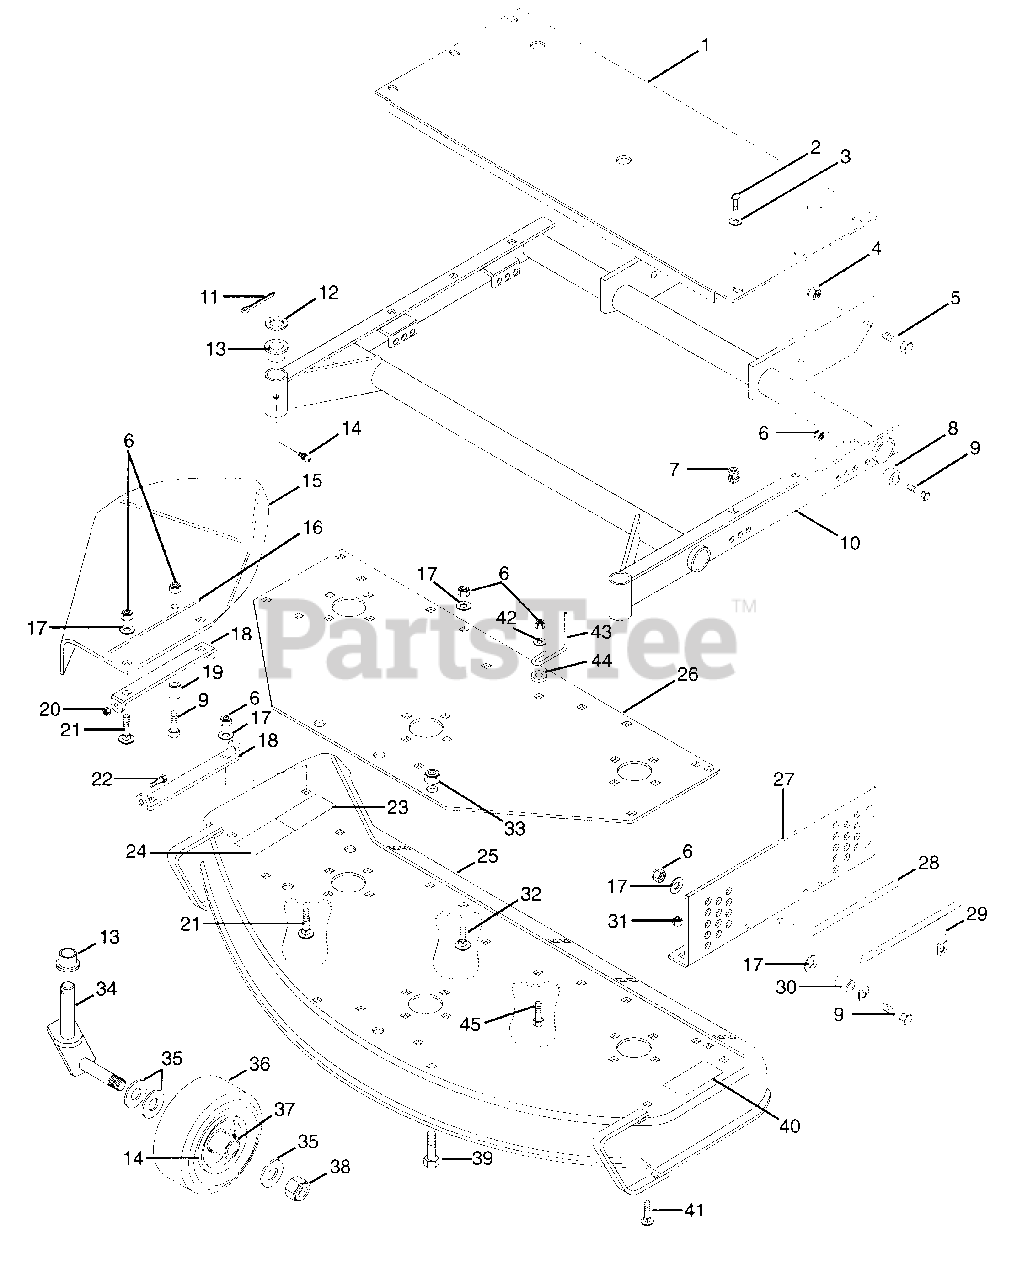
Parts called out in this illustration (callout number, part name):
1	Guard, 50" Mower Belt
2	Screw-Tapping .25-20 x .50
3	Washer-Flat-Steel .281 x .620 x .065
4	Nut-Locking-Nylon .625-11 Grade 2
5	Bolt-Hex .625-11 x 1.50
6	Nut-Locking-Nylon .375-16 Grade 2
7	Grommet, Plastic
8	Bushing .391 x .626 x .670
9	Bolt-Hex .38-16 x 1.50 Grade 5
10	Mower Frame, 50", Pro 150
11	Pin-Cotter .188 x 1.50
12	Washer-Hardened Trust 1.002 x 1.552 x .030
13	Bushing-Flange 1.020 x 1.385 x .75 x 1.75
14	Fitting-Lube .25-28 x .256
15	Shield, Safety External 50" Mower
16	Width of Cut Decal
17	Washer-Flat-Steel .406 x .812 x .065
18	Bracket, Chute
19	Bushing-Sleeve .407 x .625 x .750
20	Nut-Locking-Nylon .250-20 Grade 2
21	Bolt-Round Head Square Neck .38-16 x 1.0
22	Bolt-Hex .25-20 x .875
23	Decal, Danger Hand
24	Decal, Warning Eye
25	Weldment, 50" Mower
26	Plate, Support 1
27	Bracket, Mower Side Support Left Hand
27	Bracket, Mower Side Support Right Hand
28	Pin, Mower Locking
29	Handle
30	Bushing
31	Nut-Locking-Nylon .312-18 Grade 2
32	Bolt-Round Head Square Neck .375-16 x .75 Grade 1
33	Nut-Locking-Nylon .50-13 Grade 5
34	Weldment, Caster Fork
35	Washer-Flat .812 x 1.469 x .134
36	Wheel 9 x 3.50
37	Bearing, Ball
38	Nut-Locking-Nylon .75-10 Grade 2
39	Bolt-Hex .50-13 x 1.25 Grade 5
40	Decal, Danger Foot
41	Bolt, Round Head Square Neck .31-18 x 1.0
42	Washer-Flat-Steel .406 x 1.000 x .188
43	Belt Brake Finger 2-Deck Clutch
44	Bushing Flange .383 x .50 x .165
45	Bolt-Hex .38-16 x 1.25 Grade 5
45	Bolt-Round Head Square Neck .38-16 x 1.25
